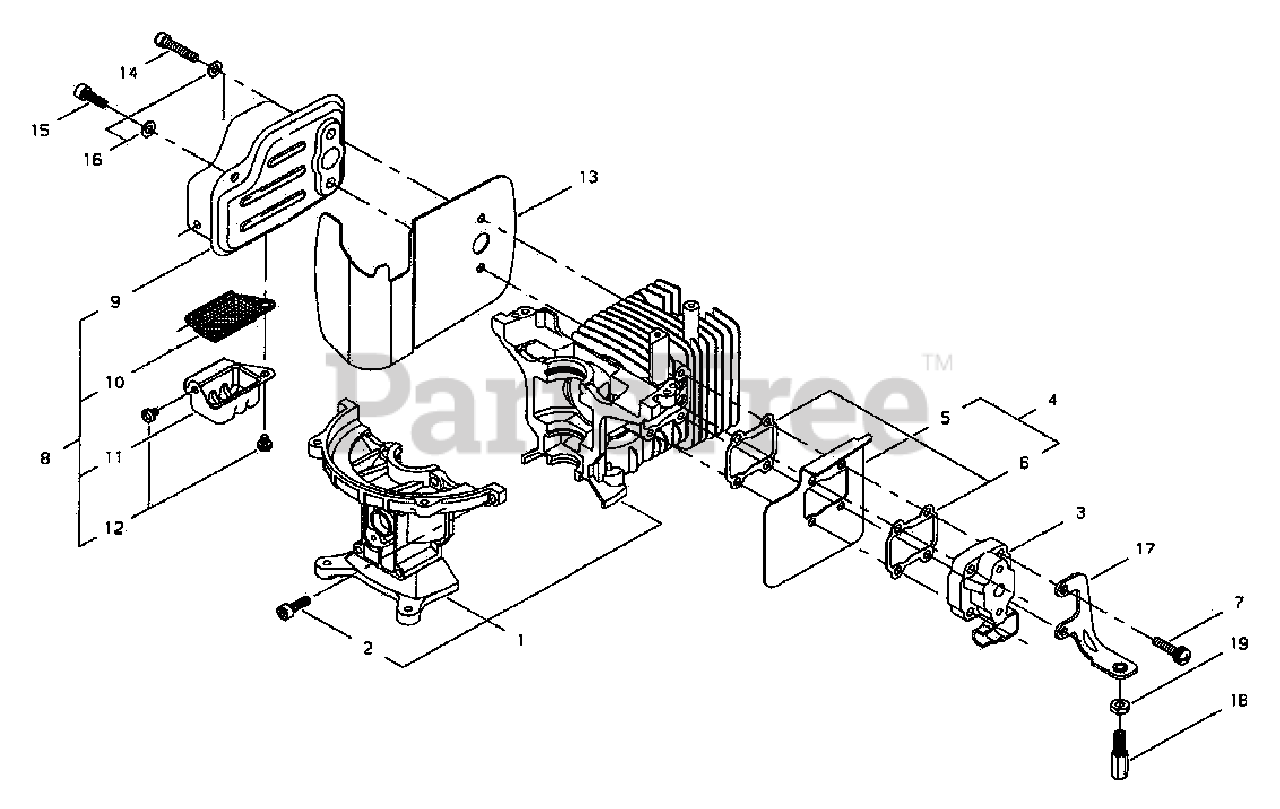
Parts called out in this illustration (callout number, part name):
1	CYLINDER BLOCK SET
2	BOLT 5×16
3	INSULATOR WITH REED VALVE
4	SHIELD ASSY, INTAKE HEAT
5	HEAT SHIELD, INTAKE
6	GASKET, EXHAUST
7	SCREW M5×22
8	MUFFLER ASSY
9	MUFFLER
10	SCREEN, SPARK ARRESTER
11	GUIDE, EXHAUST
12	SCREW M4×6
13	HEAT SHIELD, EXHAUST
14	BOLT M5×25
15	BOLT 5×16
16	WASHER, FLAT 5.5×10×0.8
17	BRACKET, THROTTLE CABLE
18	ADJUSTER, THROTTLE CABLE
19	NUT, ADJUSTER LOCK M6
